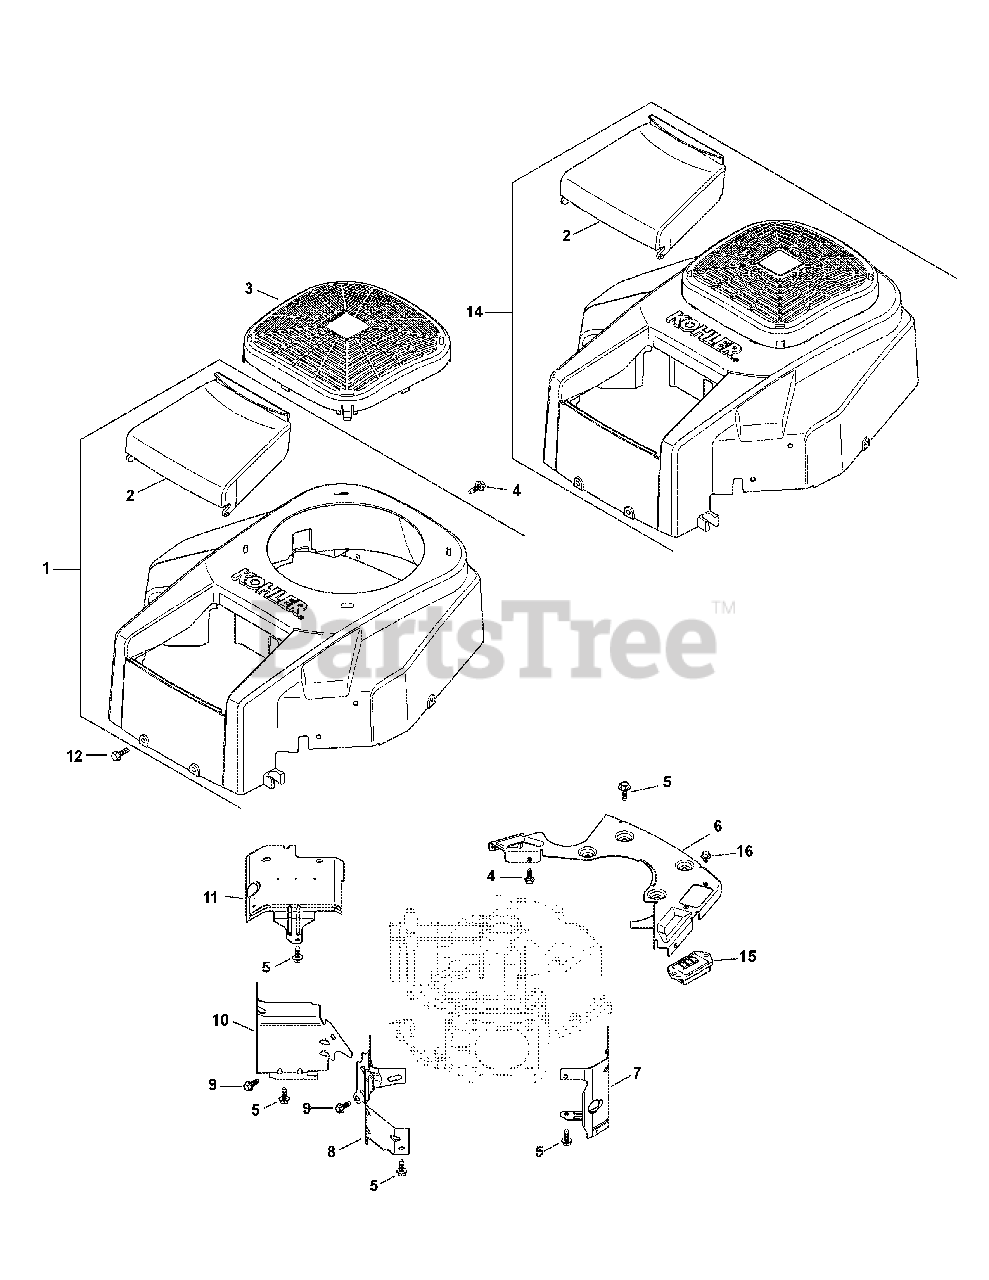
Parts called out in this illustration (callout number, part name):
1	Housing Blower Kit
2	Air Cleaner Cover
4	Flg. Thd. Frm. Screw, M5 x 0.8 x 16
5	Flg. Thd. Frm. Screw, M6 x 1.0 x 16
6	Backing Plate Kit
7	Cyl Barrel Baffle - #2 Side
8	Valley Baffle - #2 Side
9	Flg. Thd. Frm. Screw, M5 x .8 x 10
10	Valley Baffle - #1 Side
11	Cyl Barrel Baffle - #1 Side
12	Tap Screw, M6 x 1.7 x 18
15	Regulator/Rectifier
16	Flng. Thd. Frm. Screw, M6 x 1.0 x 10
